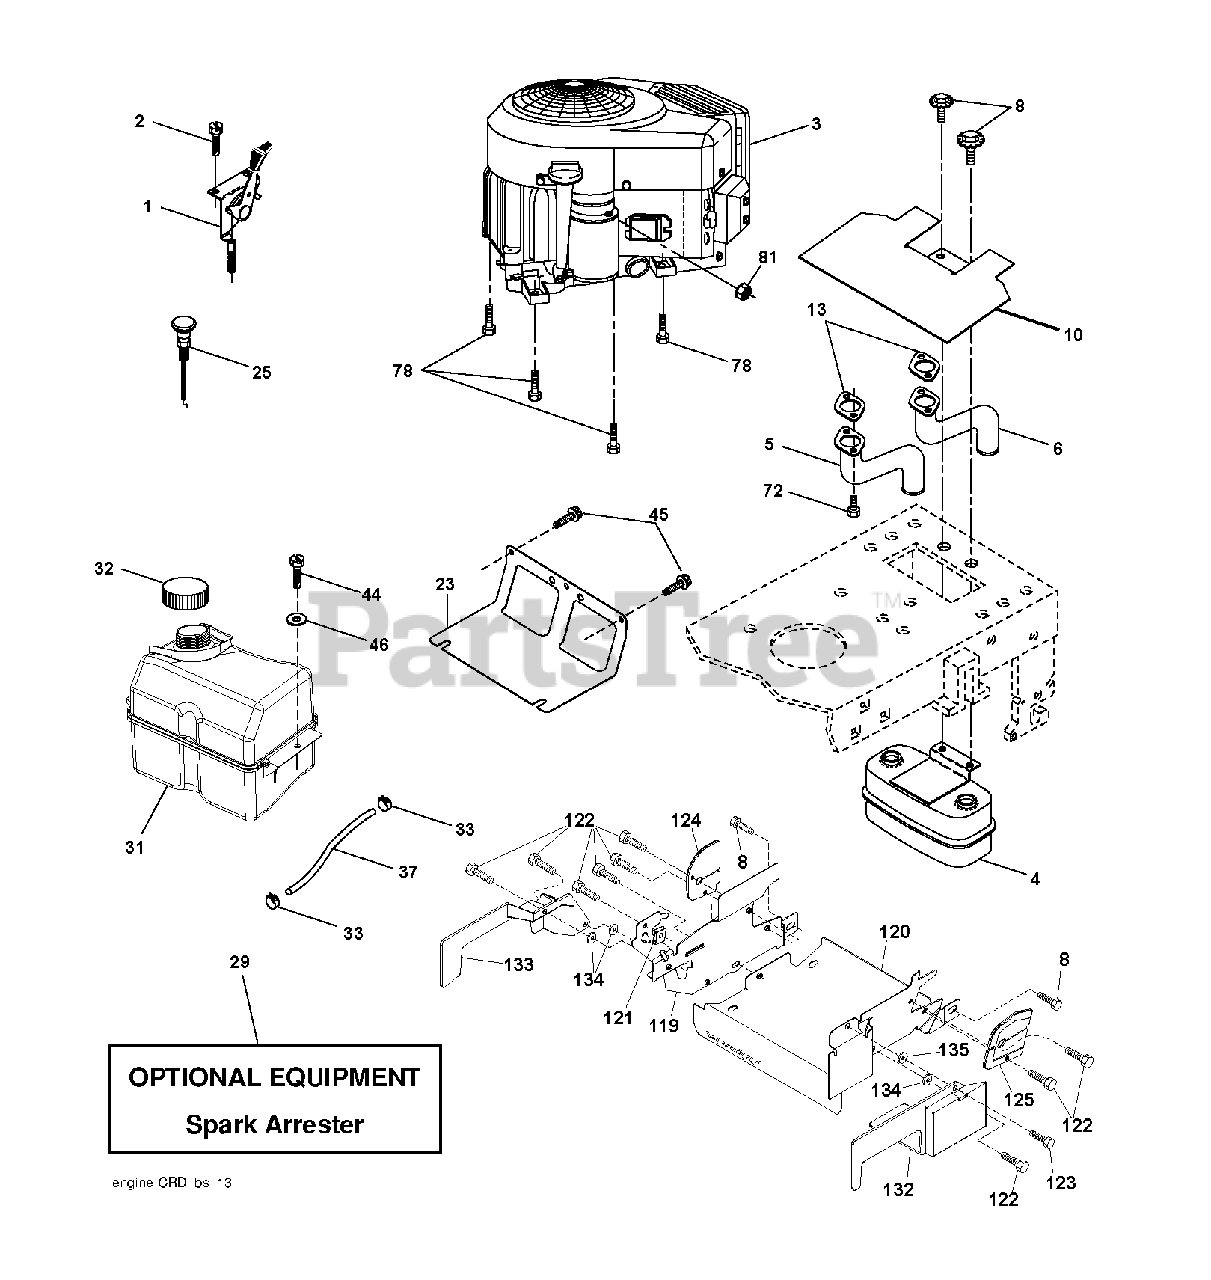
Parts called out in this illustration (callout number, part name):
1	CONTROL, THROTTLE
2	SCREW
4	MUFFLER.TWIN.CYL.LOW.TONE
5	EXHAUST TUBE RH
6	TUBE MANIFOLD LH
8	BOLT, 5/16-18 X 1 3/4
10	RP SHIELD HEAT MUFFLER
13	GASKET.MUFFLER
23	SHEILD.BROWNING.DBR.GUARD
29	ARRESTER SPARK (OPTIONAL)
32	FUEL CAP
33	HOSE CLAMP
37	LINE.FUEL.20
44	SCREW HEXWSHR 1/4-20X3/4
45	SCREW, 3/8-16X3/4
72	SCREW.SOCKET.HEAD.5/16-18
78	SCREW.3/8-16
81	NUT
122	SCREW.1/4-20X5/8
123	SCREW, 5/16-18 X 1/2
134	PALNUT 1/4
